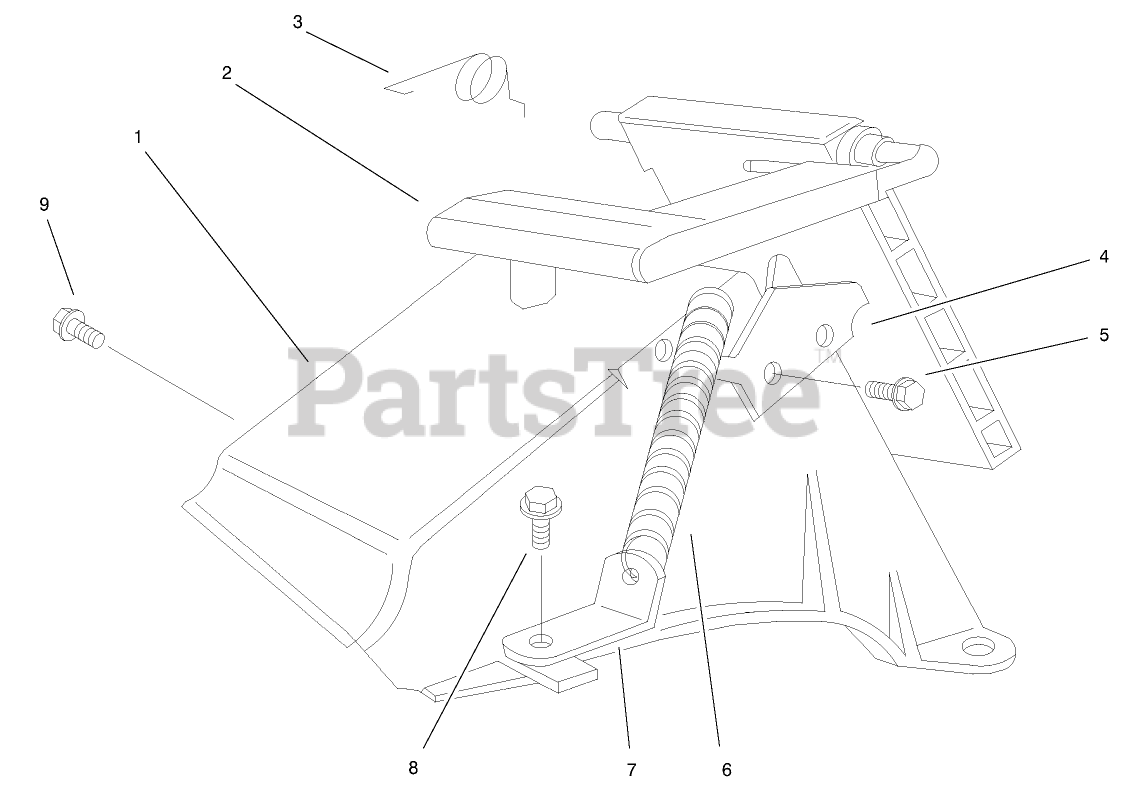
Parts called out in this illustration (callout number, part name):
1	TUNNEL-DISCHARGE
2	DISCHARGE DOOR ASM
3	SPRING-DOOR
4	LATCH-PLATE
5	SCREW-PLASTITE
6	RETAINER-DOOR
7	BRACKET-SPRING
8	SCREW-HWH
9	SCREW AND WASHER ASM
